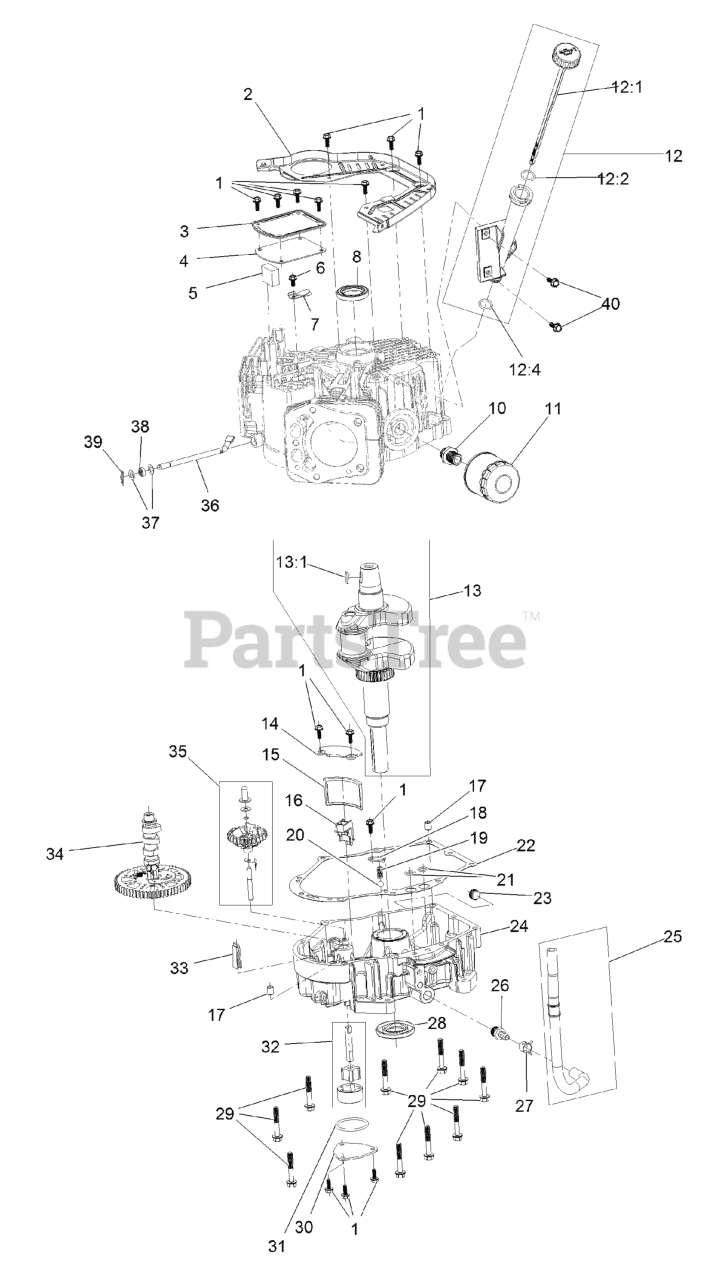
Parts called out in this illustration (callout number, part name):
1	SCREW-HHF
3	COVER-BREATHER
4	GASKET-BREATHER
5	FILTER-BREATHER
6	SCREW-HHF
7	VALVE-BREATHER
8	SEAL-OIL
10	ADAPTOR-FILTER, OIL
11	FILTER-OIL
12	OIL TUBE ASM
12:1	DIPSTICK
13	CRANKSHAFT
13:1	KEY-WOODRUFF
14	COVER-SCREEN, OIL
15	SCREEN-OIL
16	RETAINER-SCREEN
17	PIN-DOWEL
18	PLATE-RETAINER
20	VALVE-BALL
22	GASKET-COVER, CRANKCASE
23	PLUG-DRAIN
24	COVER-CRANKCASE
25	OIL DRAIN HOSE ASM
26	FITTING-HOSE
27	CLAMP-HOSE
29	SCREW-HHF
30	COVER-OIL PUMP
32	OIL PUMP ASM
33	DEFLECTOR-OIL, RUBBER
34	CAMSHAFT
35	GOVERNOR ASM
36	SHAFT-GOVERNOR
37	WASHER-PLAIN
38	SEAL-OIL
39	PIN-HAIR
40	SCREW-HHF
